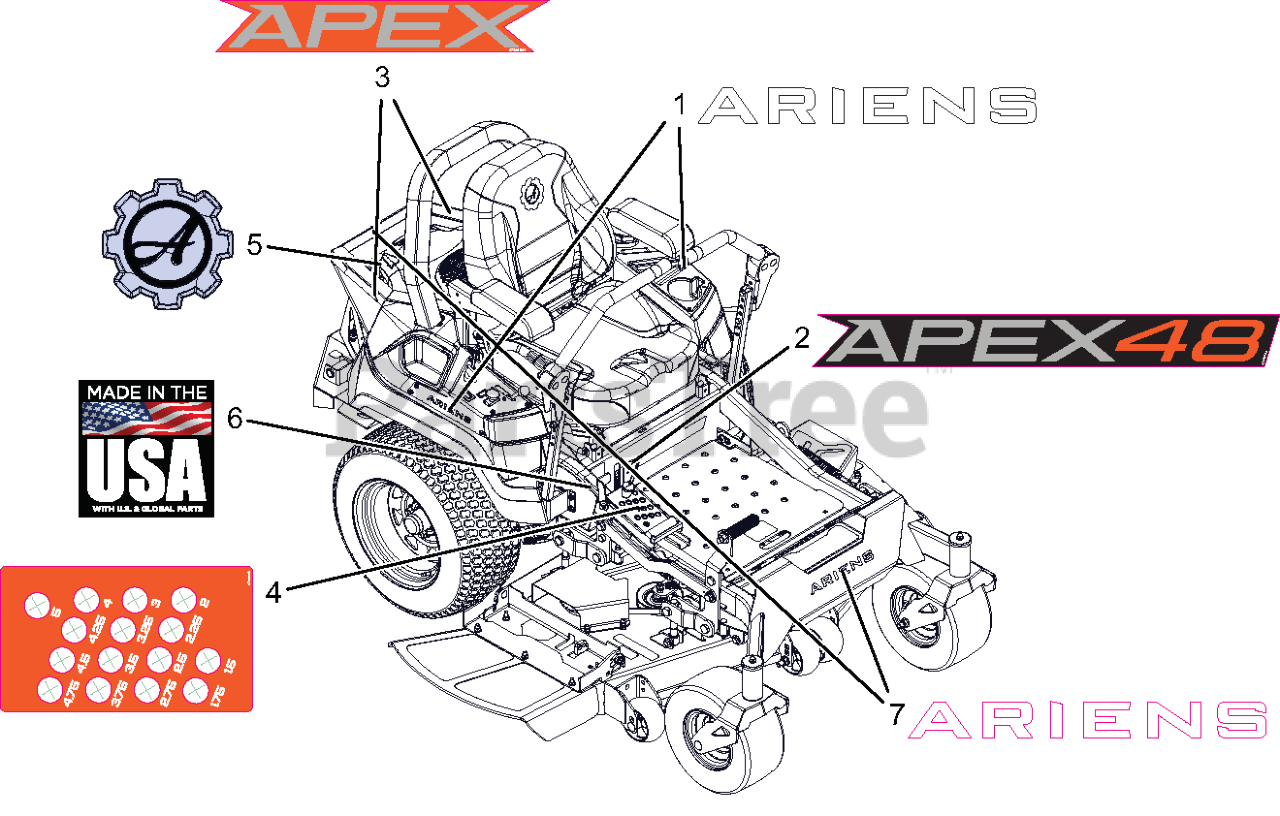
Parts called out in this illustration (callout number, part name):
1	DECAL, ARIENS (6.50")
2	DECAL, 48" APEX KICKPLATE
3	DECAL, APEX FENDER
4	DECAL, ARIENS HOC
5	DECAL, ARIENS - GEAR BADGE
6	DECAL, MADE IN USA
7	DECAL - ARIENS 9.625"
